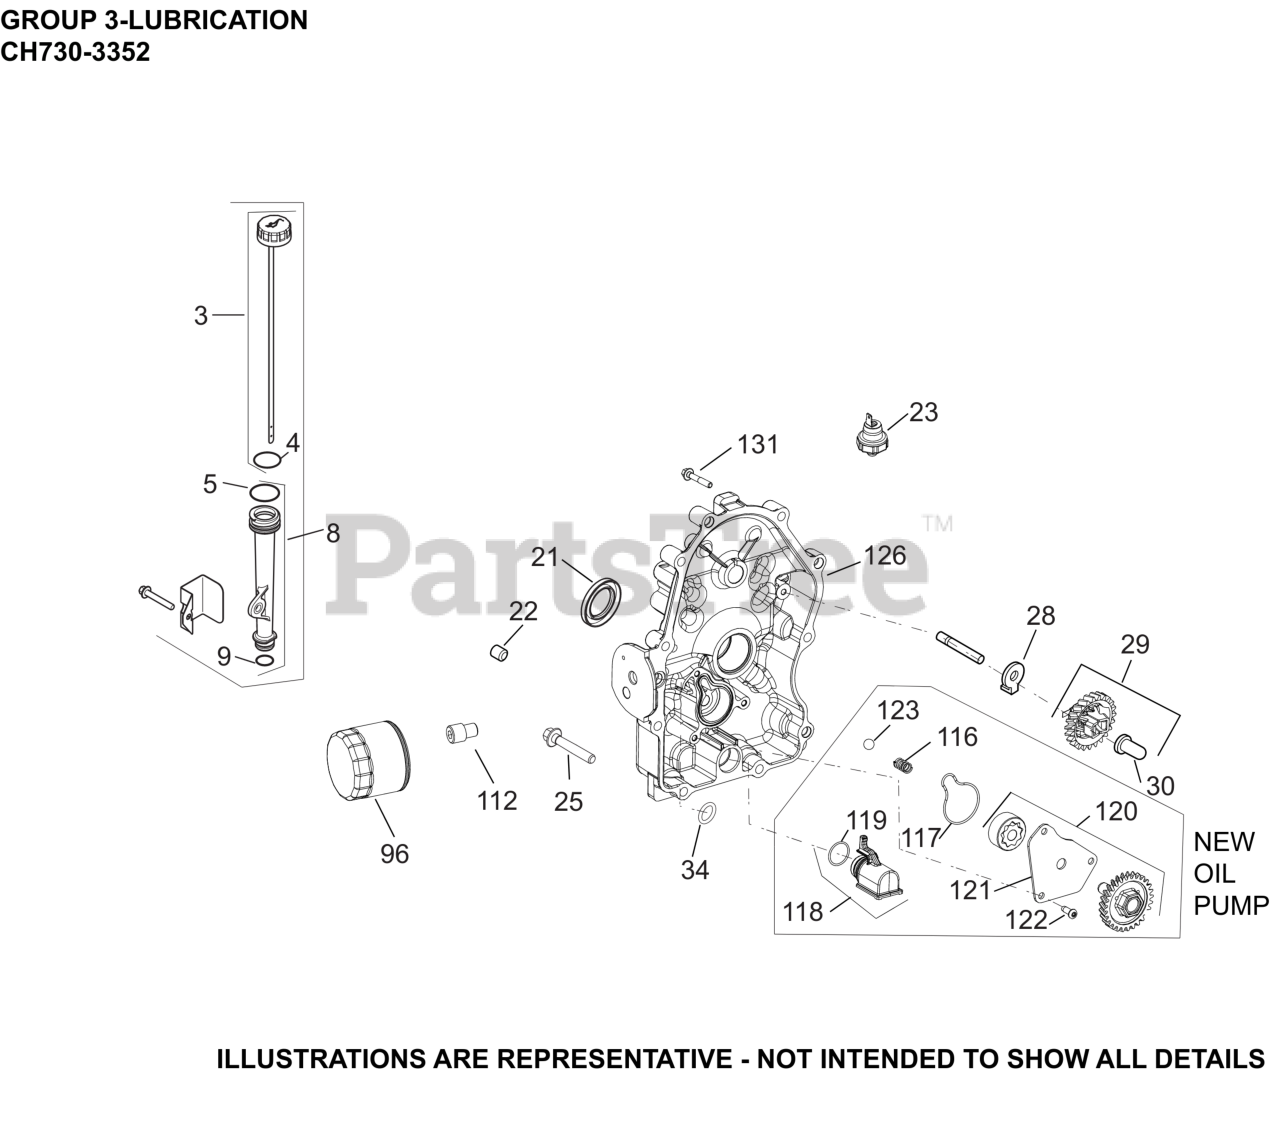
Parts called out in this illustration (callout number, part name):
3	KIT, DIPSTICK
4	O-RING, DIPSTICK
5	O-RING, UPPER OIL FILL TUBE
8	TUBE, OIL FILL ASSEMBLY
22	PLUG, CTSK PIPE 1/8"
23	SWITCH, OIL PRESSURE
25	SCREW, FLG M8X1.25X45
28	TAB, LOCKING
29	KIT, GOVERNOR GEAR W/PIN
30	PIN, GOVERNOR REGULATING
96	OIL FILTER
112	NIPPLE, OIL FILTER
116	SPRING, COMPRESSION
117	SEAL, OIL PUMP COVER
118	PICK-UP ASSEMBLY, OIL
119	O-RING, OIL PICK-UP
120	PUMP ASSEMBLY, OIL
121	COVER, OIL PUMP
122	SCREW, BUTTON HEAD
123	PRESSURE RELIEF BALL
126	CLOSURE PLATE ASSEMBLY (SERVICE)
131	SCREW, HEX FLANGE
NI	SHAFT, GOVERNOR GEAR
